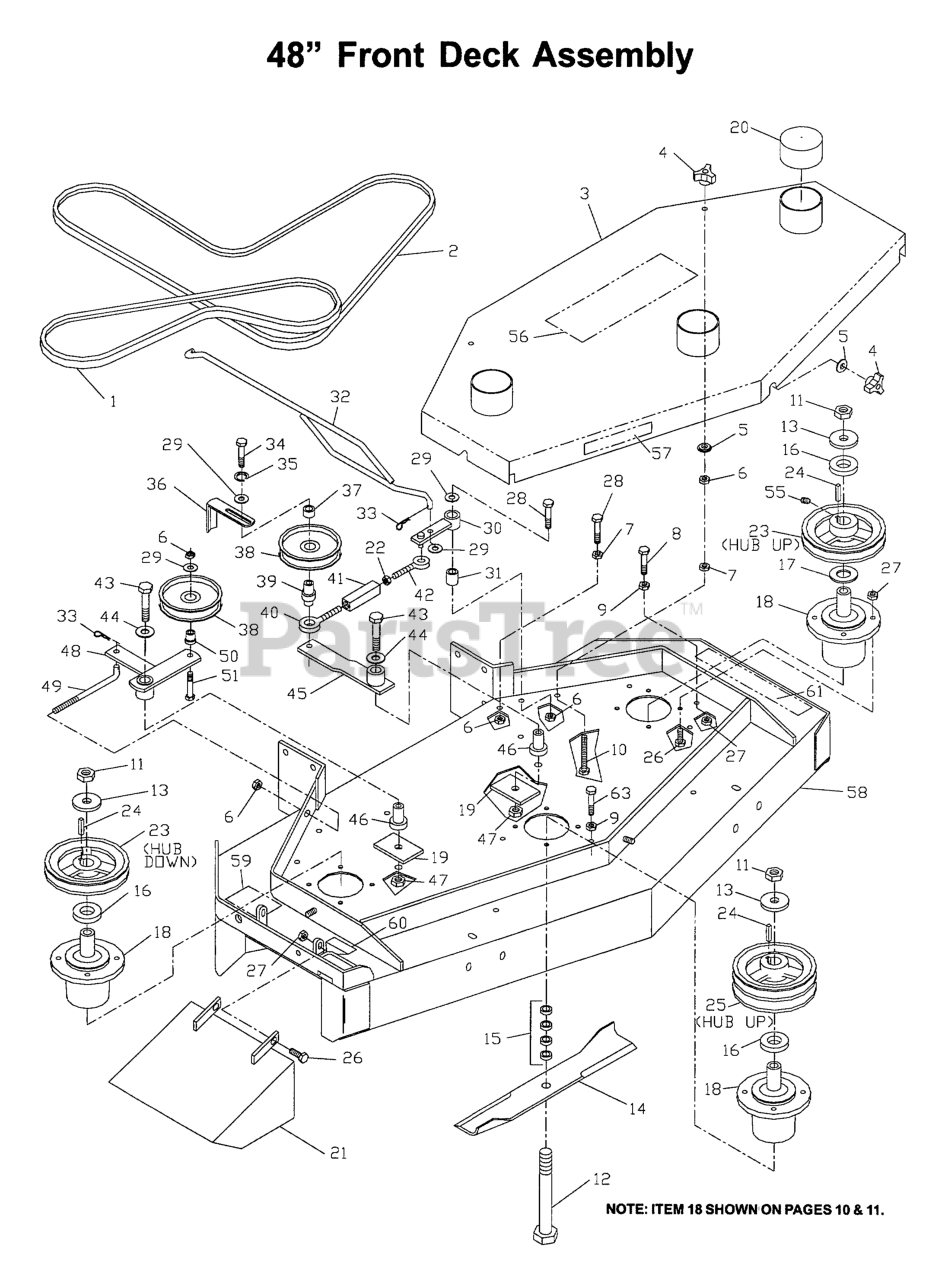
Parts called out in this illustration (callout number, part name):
1	BELT, AUX BLADE
2	BELT - ENG/DECK 48
3	BELT SHIELD 48"
4	KNOB, THREE PRONG
5	WASHER, 3/8 SEALING
6	NUT 3/8C CENTERBLOCK
7	NUT 3/8C WHIZ
8	HCS 5/16 X 3
9	NUT 5/16C WHIZ
10	TAPBOLT 3/8C X 4 1/2
11	NUT 5/8F HEX
12	HCS 5/8F X 8 1/2
13	SPINDLE WASHER
14	BLADE OEM 16 1/4"
15	BLADE SPACERS
17	MACHINERY BUSHING 10 GA.
18	HOUSING ASSEMBLY
21	DEFLECTOR CHUTE
22	NUT 5/16C HEX
23	PULLEY W/SETSCREWS
24	KEY 1/4 SQ X 1 1/8
25	PULLEY, DOUBLE W/SETS
26	HCS 5/16C X 1
27	NUT 5/16C CENTERLOCK
28	HCS 3/8C X 2 1/4
29	WASHER 3/8 FLAT
30	ENGAGEMENT ARM
31	BUSHING, SLEEVE
32	BLADE ROD 48"
33	HAIRPIN #2
34	HCS 3/8C X 2 1/2
35	SLW 3/8 STD
38	IDLER PULLEY
39	EYEBOLT PIVOT
40	EYEBOLT, LH
41	TURNBUCKLE
42	EYEBOLT, RH
43	HCS 1/2C X 2 3/4
44	WASHER 1/2 FLAT
45	ARM WELDMENT
46	IDLER SPINDLE
47	NUT 1/2-13 HEX NYLOC ZD
48	IDLER ARM, AUX.
49	TENSION ROD
50	BUSHING, IDLER FLANGE
51	HCS 3/8-16 X 1 3/4 GR5
52	HCS 7/16C X 1 1/2
53	WASHER 7/16 LOCK
54	NUT 7/16C HEX
55	SET SCREW 5/16 NYLOC
56	DECAL, HUSQVARNA 17.5"
57	DECAL, NASCAR
58	DECK W/DECALS 48"
59	DECAL, EURO SEVERING
60	DECAL, CPSC
63	HCS 5/16C X 4
64	DECAL, ETS
539101100	HCS 5/8-18 X 9 GR5 ZD
